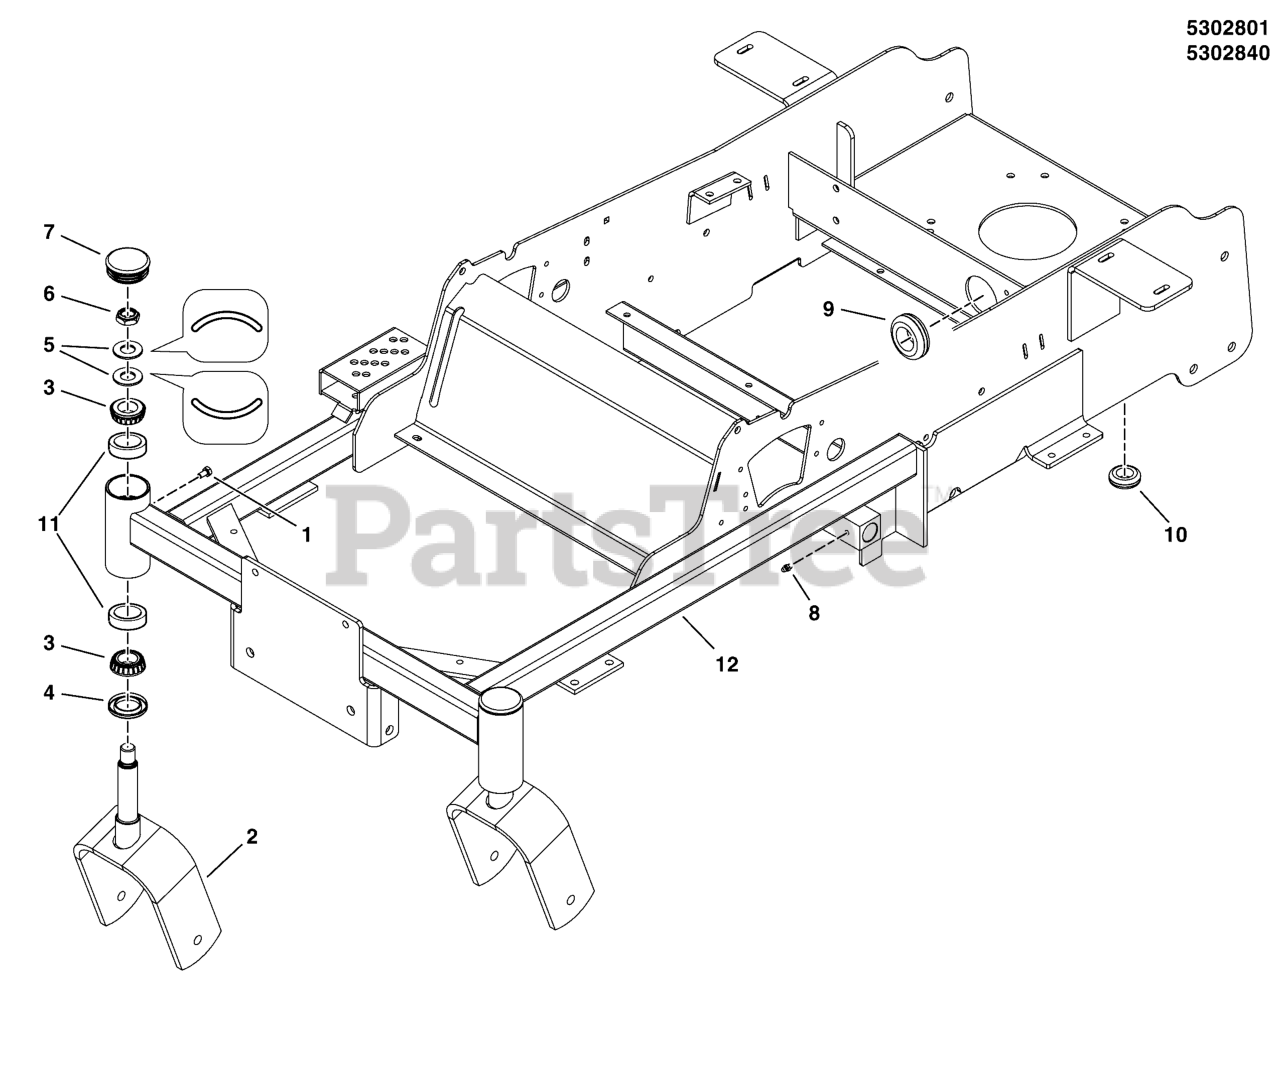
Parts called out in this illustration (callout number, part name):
1	BOLT, 1/4-28 X 1/2, GD5 YZ
2	WELD, CASTER YOKE - RED
3	BEARING, TAPERED ROLLER, 1"
4	SEAL, GREASE
5	WASHER, BELLEVILLE - 1.500 X .755
6	NUT, 3/4-16, HEX JAM NYLON LOCK
7	CAP, GREASE, LOW PROFILE
8	GREASE FITTING, 1/4-28 STRAIGHT
9	GROMMET, 2" ID
10	GROMMET, 7/8
11	CUP, BEARING (SV)
12	* WELD, MAIN FRAME, F50XT - RED
